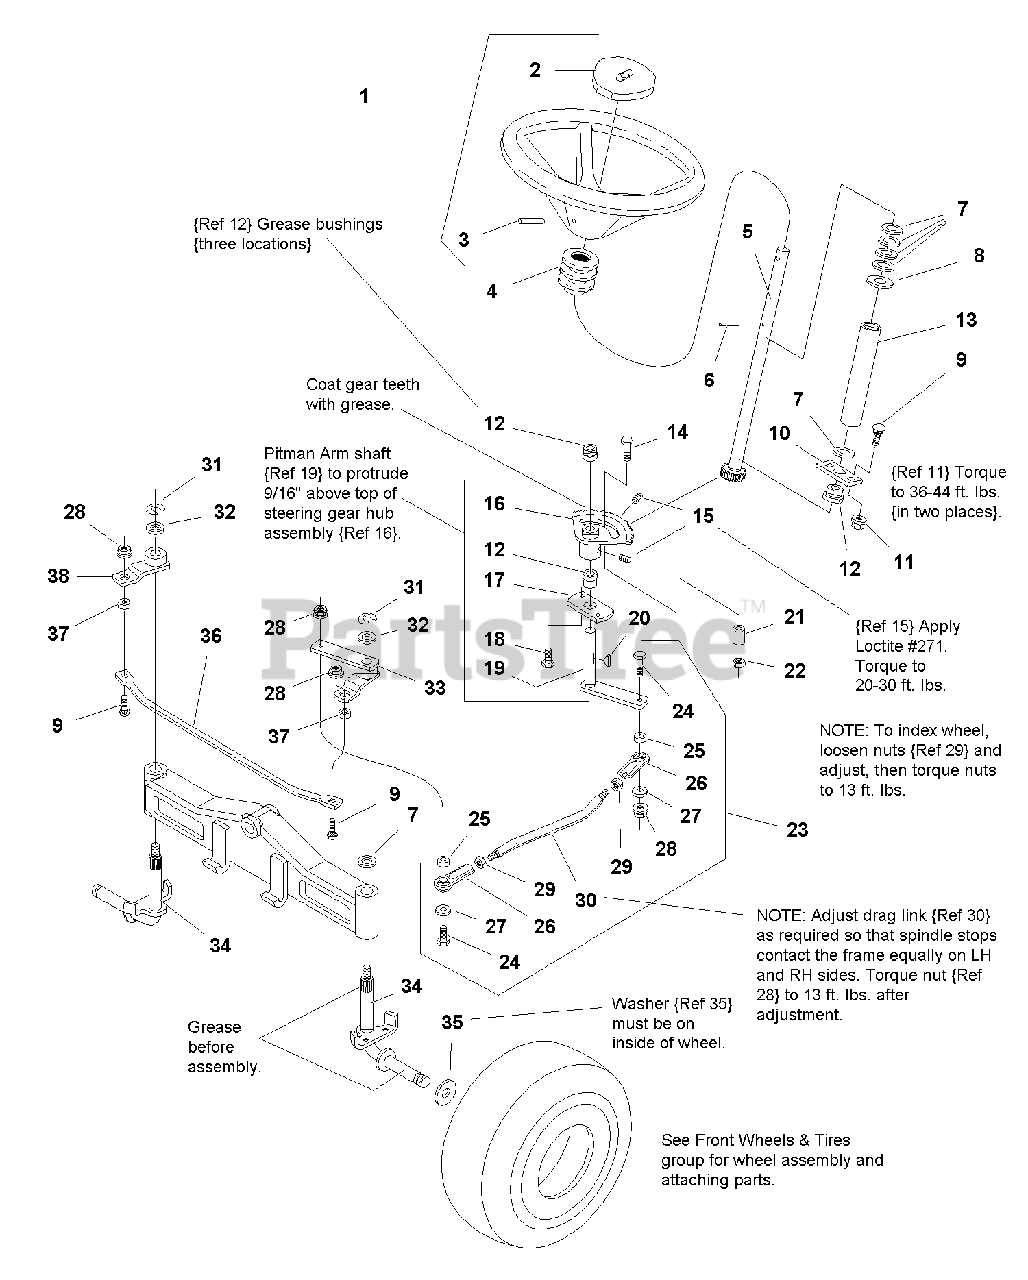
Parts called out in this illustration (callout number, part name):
1	STEERING WHEEL ASSEMBLY (IIncludes Ref. Nos. 2 & 3)
2	CAP, Steering Wheel
3	PIN, Spring, 5/8 x 2
4	TUBE, Steering
5	SHAFT ASSEMBLY Steering
6	COTTER PIN, 3/16 x 1-1/4
7	WASHER, Plain, 49/64
8	WASHER, Plain
9	CARRIAGE BOLT, 3/8-16 x 1
10	PLATE, Mounting, Steering
11	NUT, Hex Flange, 3/8-16
12	BUSHING, Nylon
13	TUBE, Shift
14	CAPSCREW, Hex Head, 5/16-18 x 1-1/2
15	SETSCREW, Square Head, 5/16-18 x 1/2
16	GEAR ASSEMBLY, Steering
17	SECTOR MOUNTING PLATE
18	CAPSCREW, Taptite, 5/16-18 x 1
19	PITMAN ARM ASSEMBLY
20	KEY, Hi Pro
21	SPACER, Stop
22	NUT, Hex Nylon Lock, 5/16-18
23	DRAG LINK KIT, (Includes Ref. Nos. 24, 25, 26, 27, 28, 29 & 30)
24	CAPSCREW, Hex Head, 3/8-16 x 1-3/4
26	BALL JOINT, Flat
27	WASHER, Plain, 3/8
28	NUT, Hex Flange, 2-Way Lock, 3/8-16
29	NUT, Hex Jam, 1/2-20
31	KLIP RING, 5/8
32	WASHER, 5/8
33	STEERING ARM ASSEMBLY, LH, Splined
34	SPINDLE ASSEMBLY, Splined (With Welded Cup Washer)
35	WASHER, Special
38	STEERING ARM ASSEMBLY, RH, Splined
